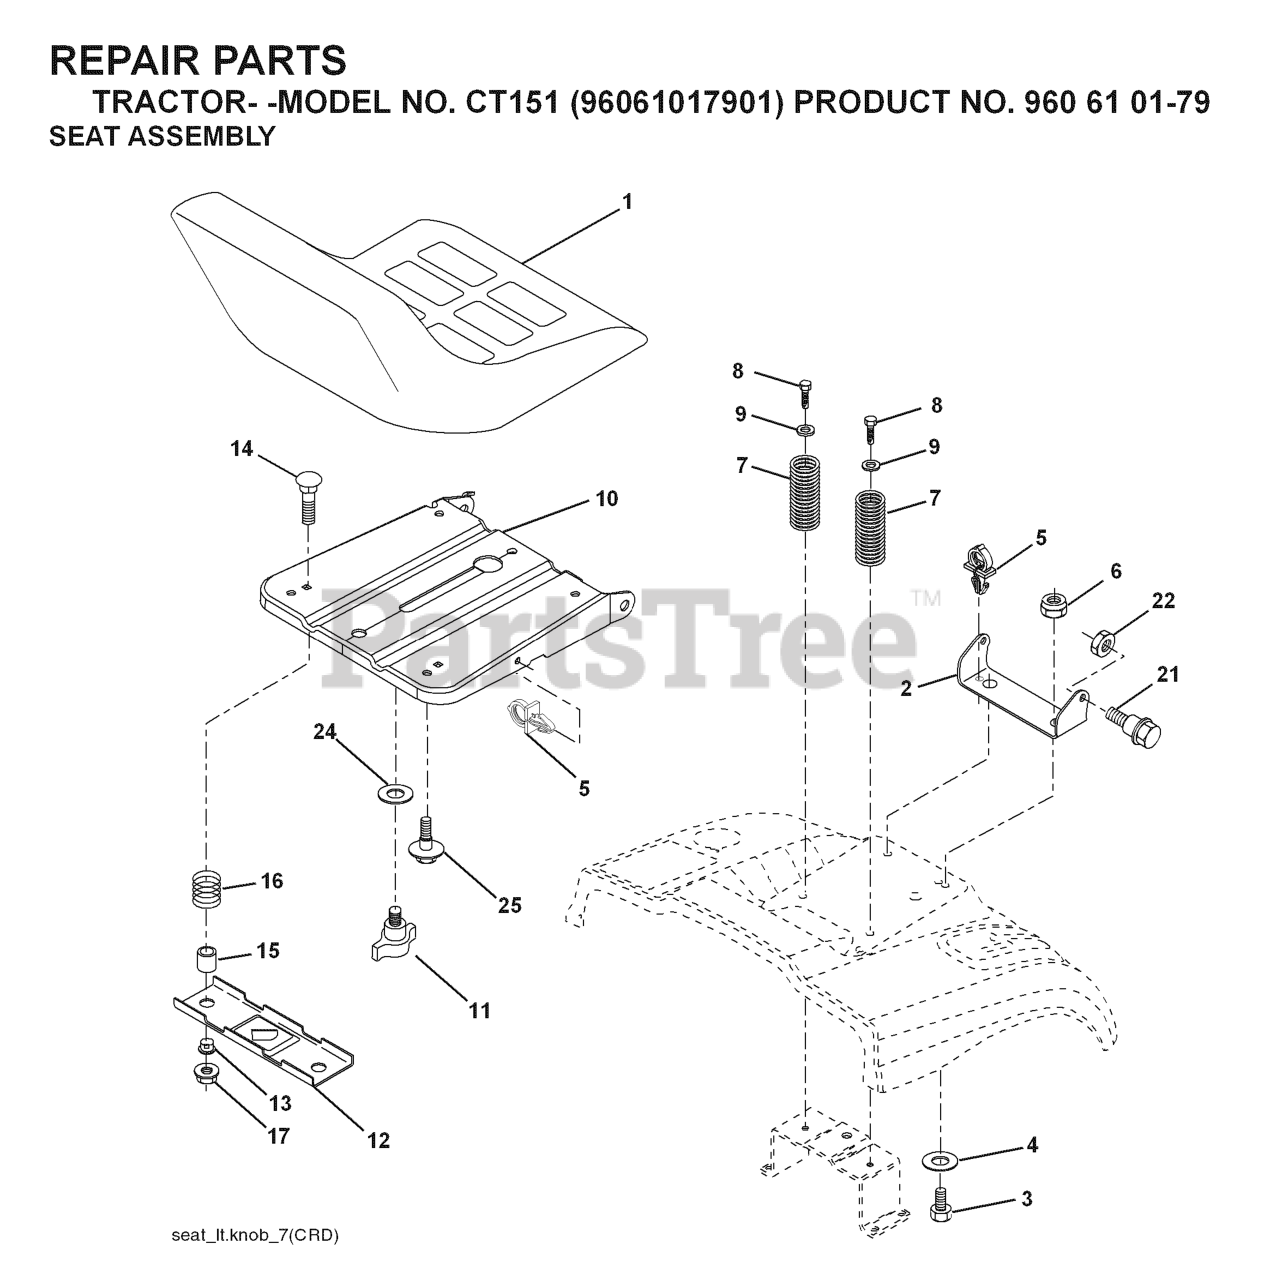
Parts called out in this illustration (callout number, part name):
1	RP SEAT
2	SEAT PIVOT BRKT
3	BOLT, HEX 3/8-16X1
6	NUT
7	SPRING COMPRESSION
8	SCREW 3/8-16X1
9	WASHER
10	PAN.ASM.SEAT.1SLOT
11	KNOB.SEAT.ADJ.WINGNUT
12	BRKT.MNTNG.SWITCH.SEAT.BLACK
14	BOLT.ROUND.HEAD.SQUARE.NECK
15	SPACER SPLIT 28X.96
17	NUT T
21	BOLT.SHOULDER.5/16-18
22	NUT.71038.31-18.HEX.NYLOCK
25	BOLT,SHOULD
